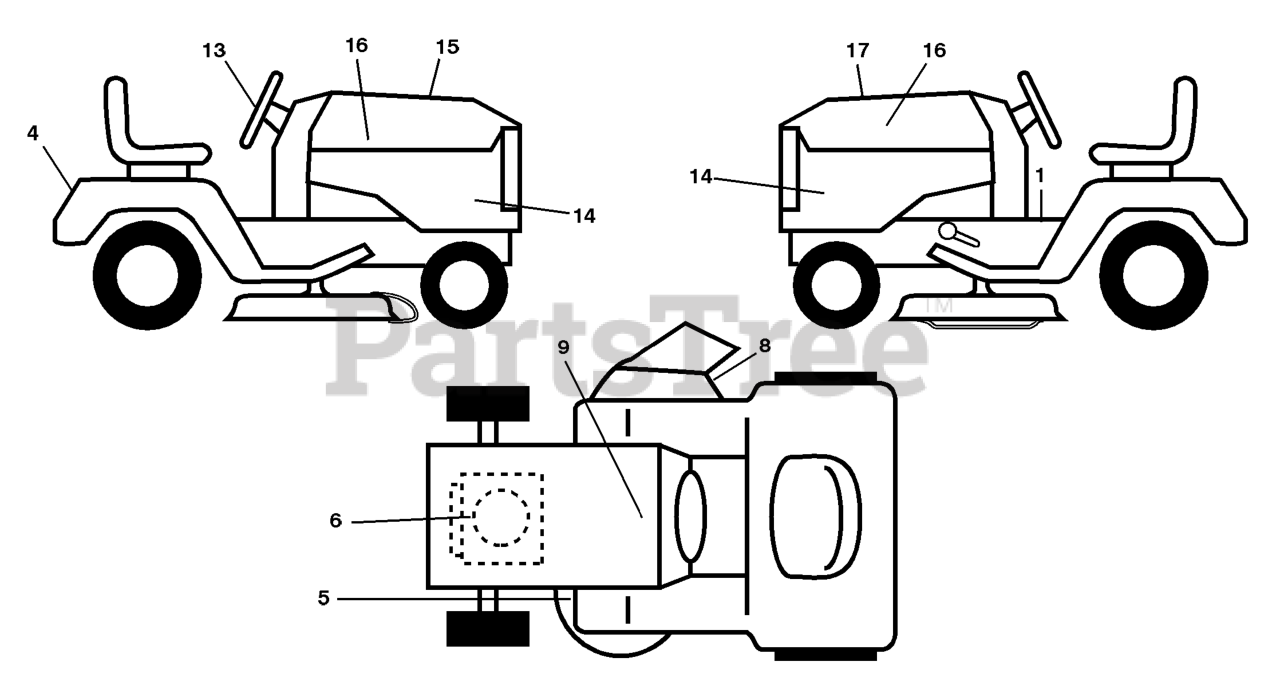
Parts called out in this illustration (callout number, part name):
1	DECAL.WARN.START.INSTRUCTIONS
4	DECAL.FENDER
5	DECAL.MOWER
6	DECAL, ENG. HP
8	DECAL.MOWER.SCH.48/54
9	DECAL BTRY SYMBOLS
13	DECAL.WHEEL.STRG.LGN.H
14	DECAL, PANEL SIDE
15	DECAL HOOD CUST. RESP.
16	DECAL.HOOD.LOGO.HUSQVARNA
17	DECAL.RPL.BS.22INTK/HY/48E.TLT
17	DECAL.BYPASS.FENDER.CRD.LT.YT
17	PAD, FOOTREST, LH
17	PAD, FOOTREST, RH
17	Manual, Owner's
